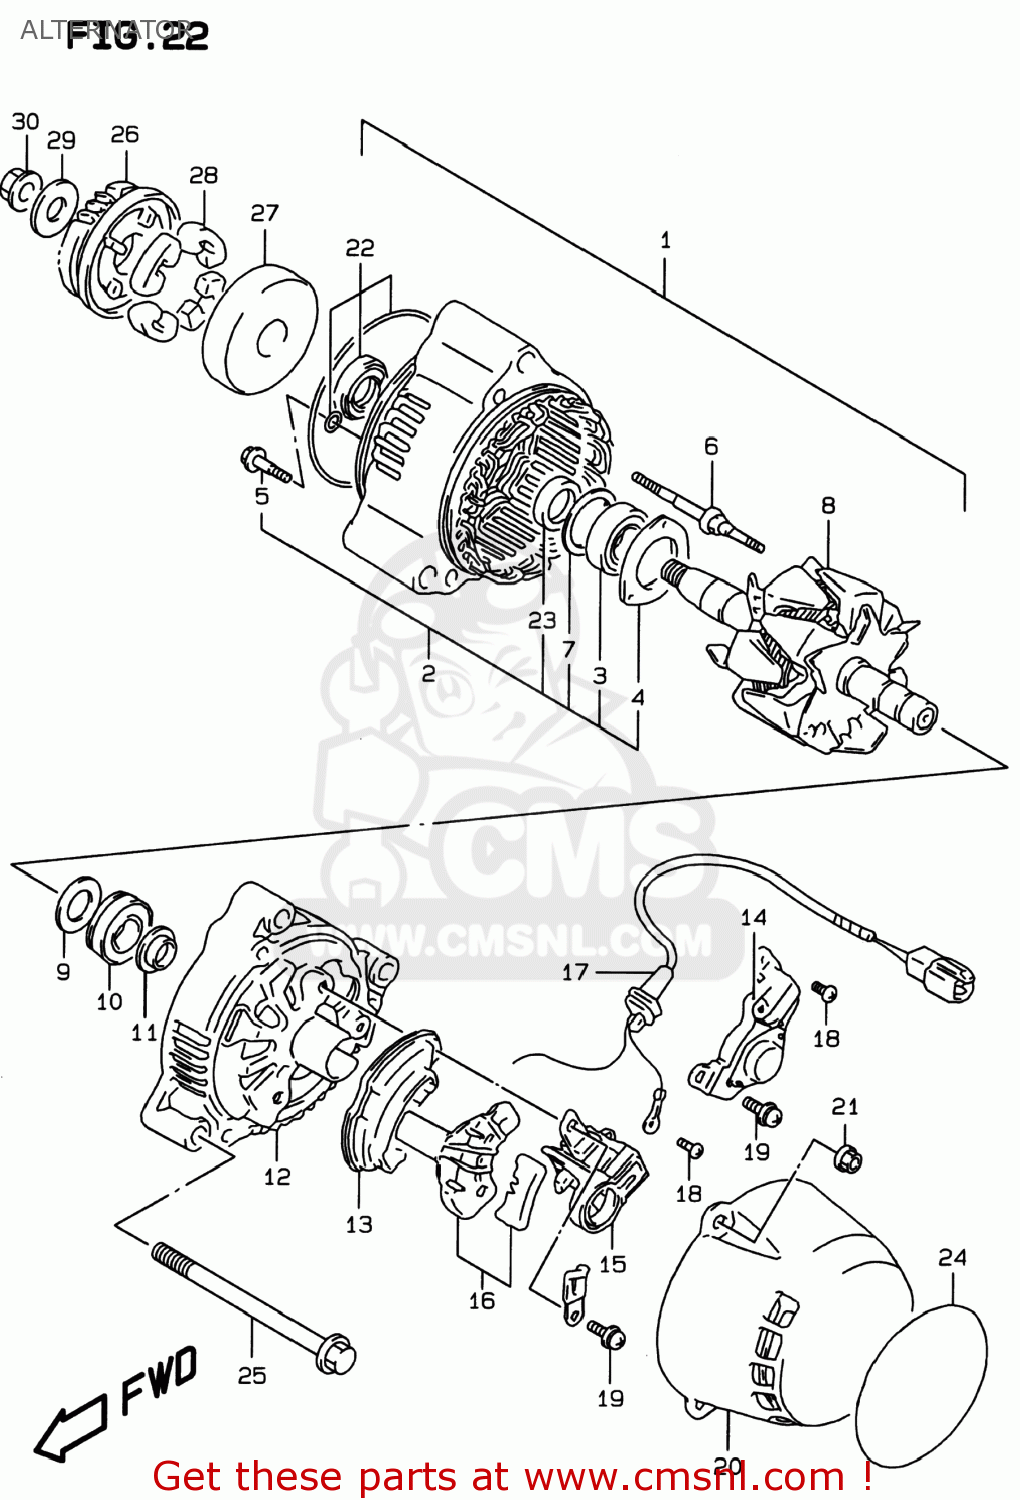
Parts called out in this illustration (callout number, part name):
1	ALTERNATOR ASSY
2	FRAME,DRIVE END
3	BEARING
4	RETAINER
5	SCREW,BEARING RETAINER
6	STUD BOLT
7	COVER,BEARING
8	ALTERNATOR ASSY
9	COVER,BEARING
10	BEARING
11	COVER(2)
12	FRAME,END
13	HOLDER,RECTIFIER
14	REGULATOR
15	HOLDER,BRUSH
16	COVER,RECTIFIER
17	WIRE,LEAD
18	SCREW 4X6
19	SCREW
20	COVER
21	NUT
22	SERVICE KIT(A)
23	SPACER
24	PROTECTOR,ALTERNATOR
25	BOLT
26	GEAR,GENERATOR DRIVEN
27	HOUSING,GENERATOR GEAR
28	DAMPER,GENERATOR DRIVEN
29	WASHER
30	NUT
